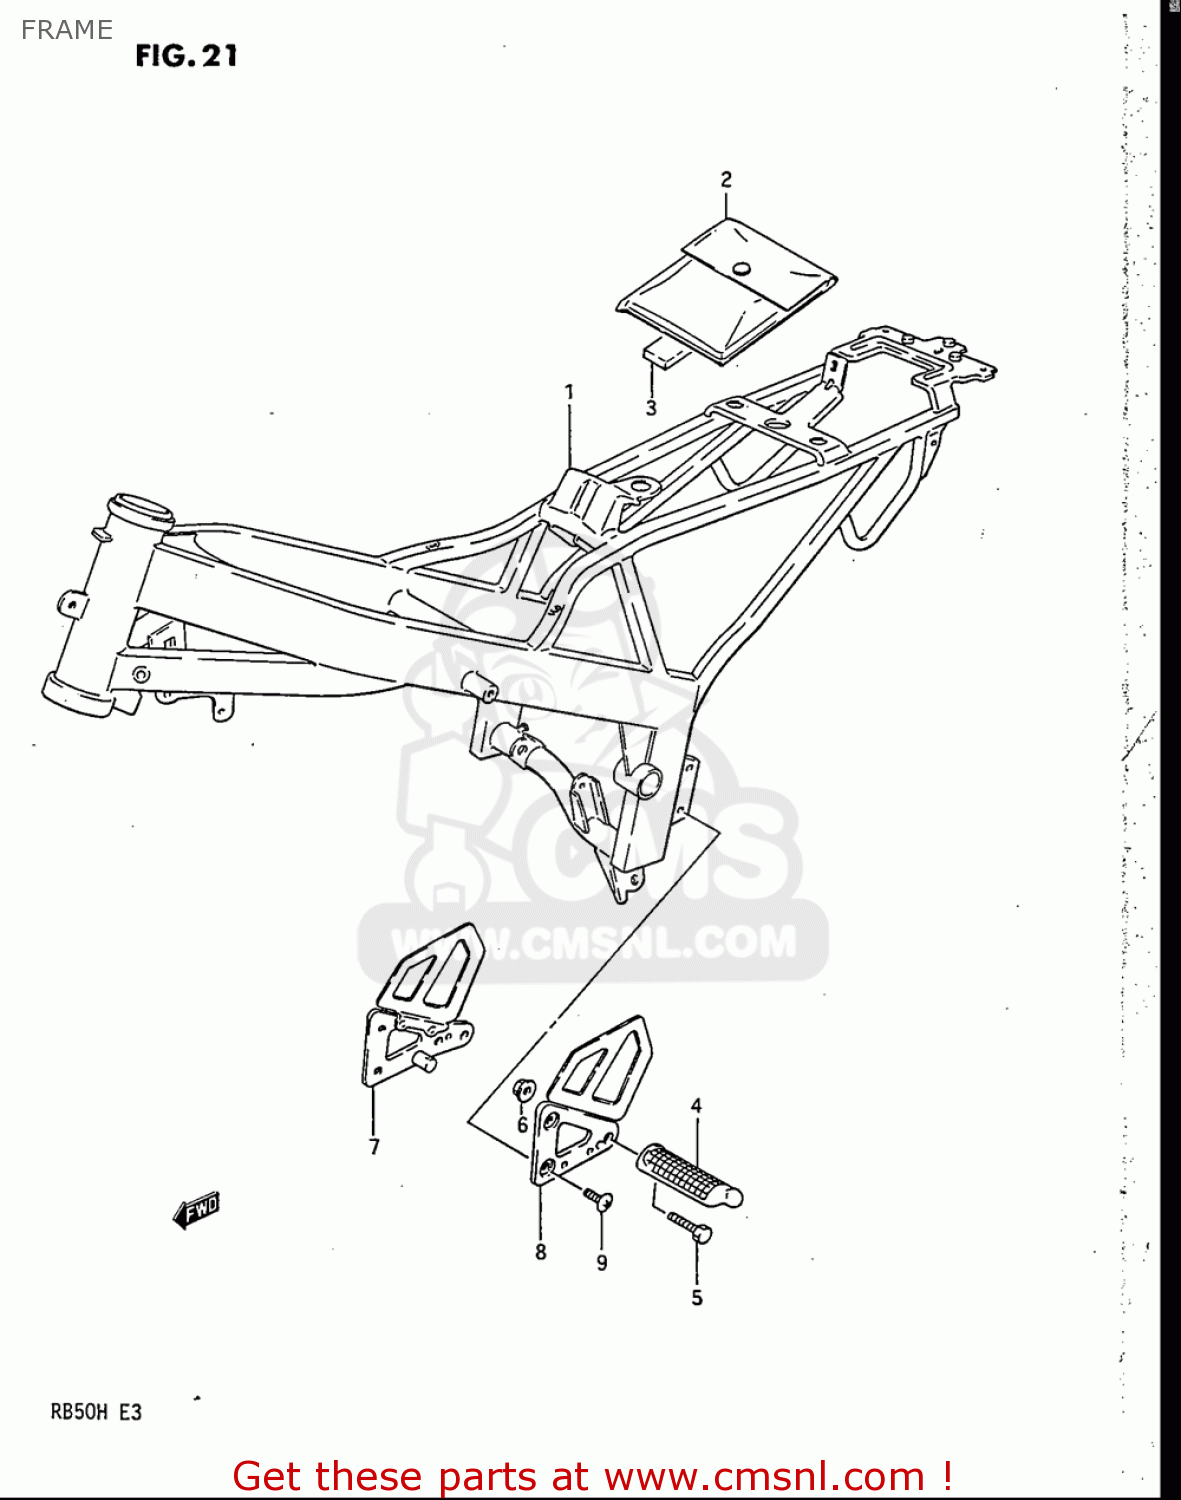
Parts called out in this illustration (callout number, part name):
2	BAG COMP,OWNERS MANUAL
3	FASTENER,MANUAL BAG
4	BAR,FR FOOTREST
5	BOLT
6	NUT
8	BRACKET COMP,FRONT FOOTREST
9	BOLT(6X12)
